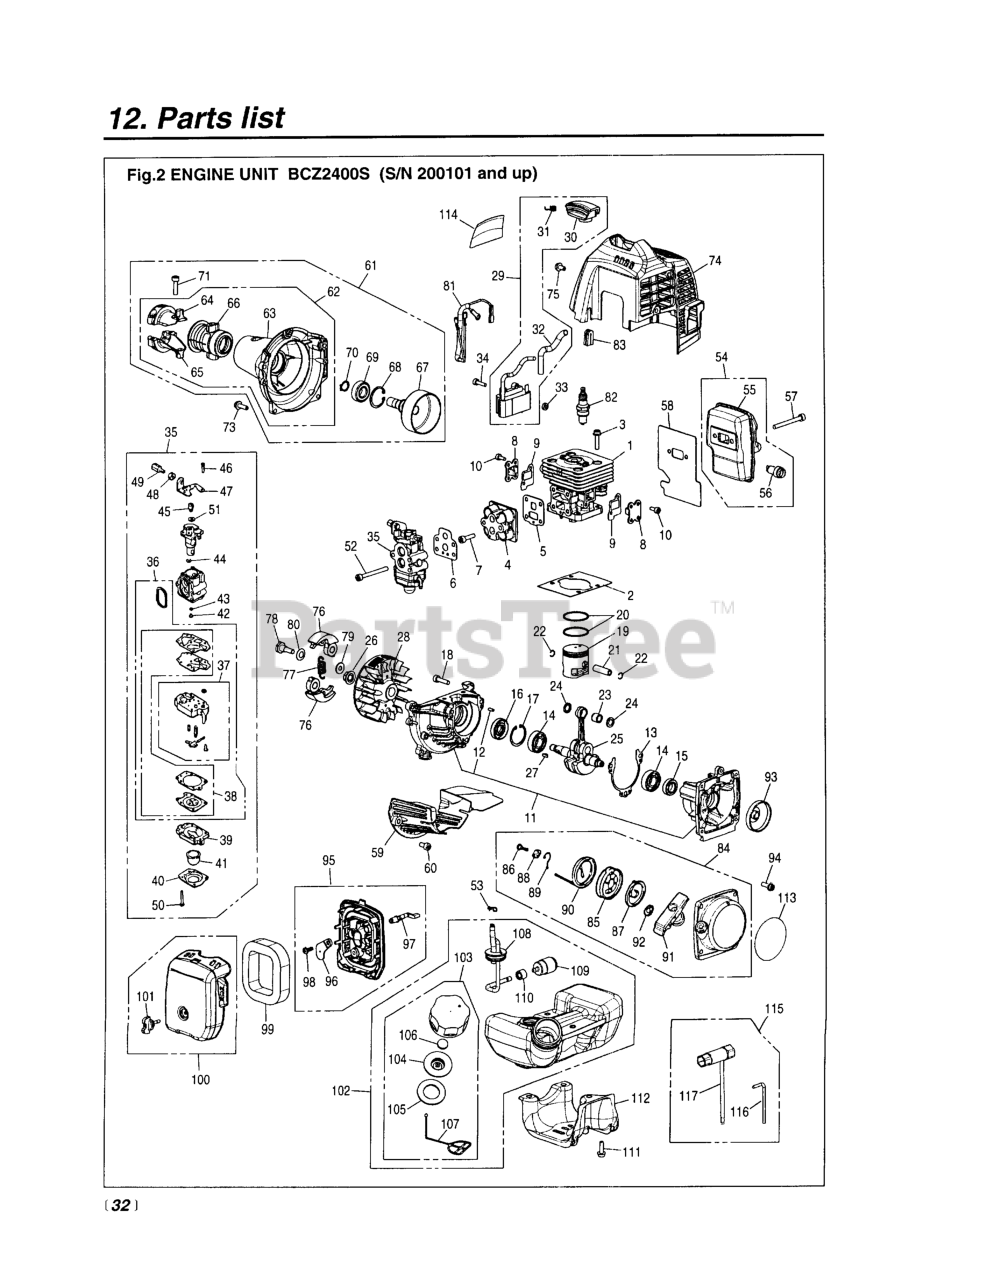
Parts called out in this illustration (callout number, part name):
1	CYLINDER
2	GASKET, BASE
3	BOLT
4	INSULATOR
5	GASKET, INSULATOR
6	GASKET, CARB.
7	BOLT, TORX
8	COVER, TR
9	GASKET, TR
10	BOLT, TORX
11	CRANKCASE-C
12	PIN
13	GASKET, CASE
14	BEARING
15	SEAL
16	SEAL, OIL (RPLS 1140-21220)
17	RING, SNAP, M28 x 1.2
18	BOLT (RPLS 2850-14220)
20	RING, PISTON
21	PIN, PISTON
22	RING, SNAP (RPLS 1101-41320)
23	BEARING
24	WASHER
25	CRANKSHAFT COMP.
27	KEY
28	ROTOR
29	COIL-A
30	CAP (RPLS 4810-72110)
31	SPRING
33	SPACER (RPLS -71260)
34	BOLT TORX
36	REBUILD KIT
37	BODY-A
38	KIT, GASKET (REPLACES-06020)
39	BODY, PURGE
40	COVER, PUMP
41	PUMP, PRIMING
42	JET
43	RING, O
44	RING
45	SWIVEL
46	SCREW
48	NUT, CABLE ADJUSTER
49	SCREW, CABLE ADJUSTER
50	SCREW
51	WASHER
52	BOLT
53	CLIP
54	MUFFLER ASSEMBLY
55	MUFFLER (REPLACES -15110)
56	ARRESTER
57	BOLT
58	GASKET, MUFFLER
59	PLATE
60	BOLT
61	PISTON (RPLS T1551-41110)
62	HOUSING COMP (RPLS. -31110)
64	BRACKET (A) (RPLS -31211)
65	BRACKET (B)
66	CUSHION (RPLS -31231)
68	RING, SNAP, M28 x 1.2
69	BEARING
70	RING, SNAP (RPLS 3130-13270)
71	BOLT (RPLS 2850-14220)
73	BOLT
74	COVER, ENGINE
76	SHOE
77	SPRING
78	BOLT
79	WASHER, FLAT (USE 182303)
80	WASHER (RPLS -51241)
81	CORD COMP.
82	SPARK PLUG (CMR7H)
83	GROMMET
84	RECOIL-A
85	REEL
86	SCREW
87	SPRING, SPIRAL
88	COLLAR
89	ARM
90	ROPE (REPLACES 4500-75160)
91	KNOB (RPLS -75420)
92	PLATE, STOPPER
93	PULLEY
94	BOLT
96	PLATE, CHOKE
97	LEVER
98	SCREW
99	ELEMENT
101	KNOB
102	TANK-A
103	CAP ASSY (RPLS -85201)
104	HOLDER (REPLACES -85230)
105	PACKING
106	FILTER
107	STOPPER
109	FILTER ASSY
111	BOLT
112	GUARD, TANK
113	LABEL, RECOIL
114	LABEL, COVER
116	BAR
